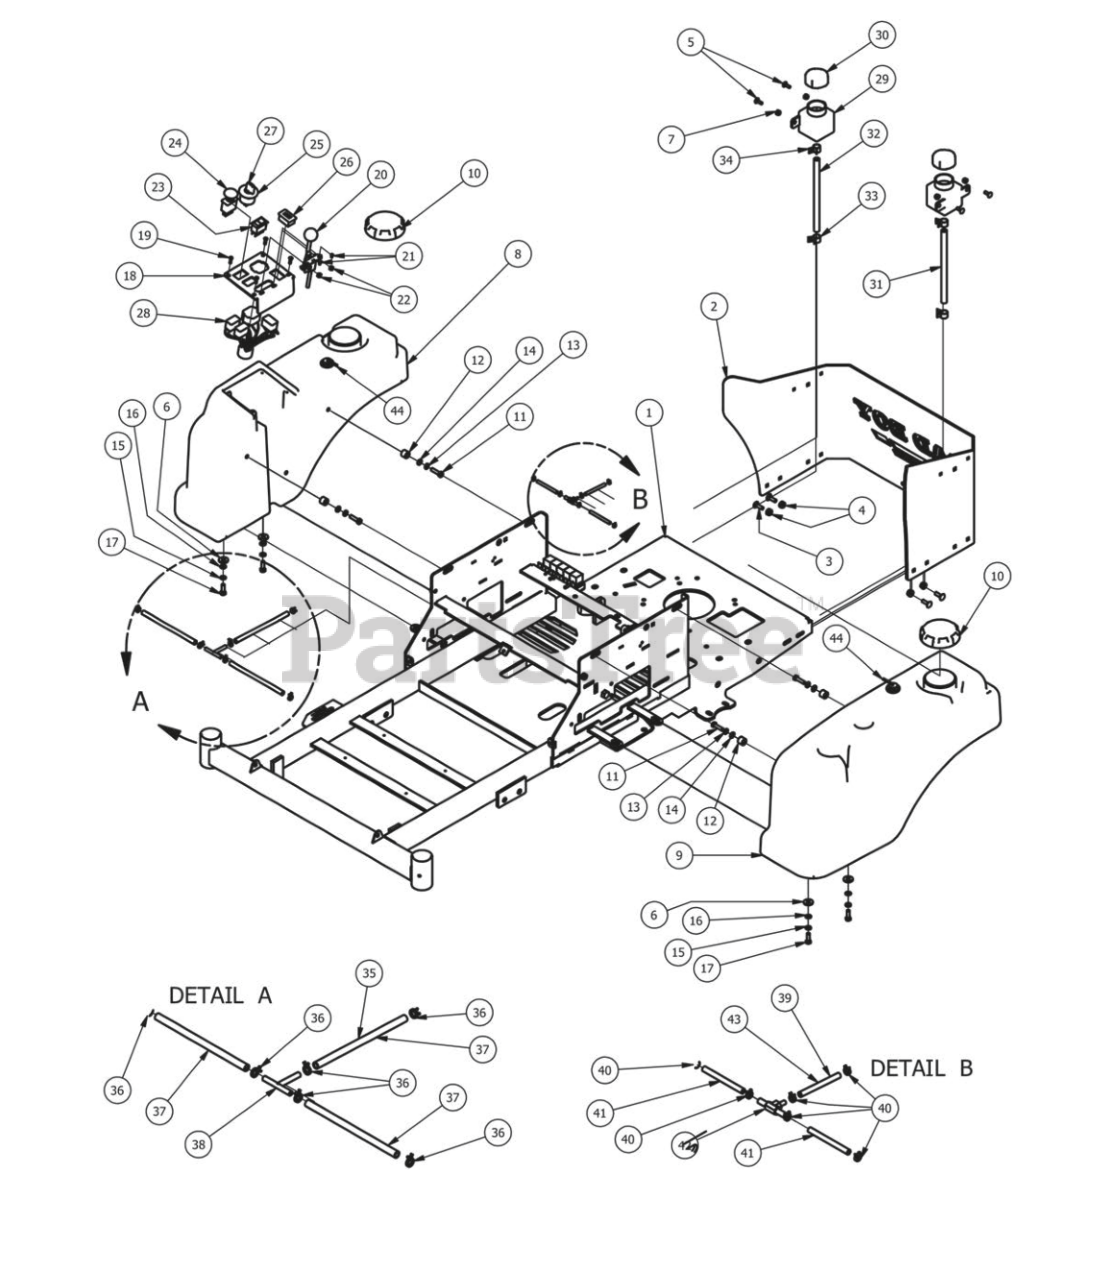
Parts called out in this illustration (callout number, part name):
1	ZT/CZT Frame 2013 Models
2	2013 ZT/CZT Rear Cover 27KO/26KA
3	5/16" x 1" Carriage Bolt
4	5/16-18 Nylon Flange Nut
5	1/4" x 3/4" Carriage Bolt
6	.360 ID Plastic Washer
7	1/4" Nylock Nut
8	Right Fuel Tank/Outlaw/2012/EPA
9	Left Fuel Tank/Outlaw/2012/EPA
11	5/16 x 1 1/4 Hex Bolt
12	.380x.735x.470 Nylon Spacer
13	5/16" Lock Washer
14	1/4" Flat Washer
15	5/16" Lock Washer
16	1/4" Flat Washer
17	5/16" x 1" Bolt
18	2013 ZT/CZT Control Panel
19	10-32 x 3/8" Button Socket Head Bolt
20	Throttle Lever Assembly
21	10-24 X 5/8 BS C/S 18-8 SS
22	10-24 Nylon Insert Locknut
23	Rocker Deck Lift Switch 2011
24	PTO Engager
25	Ignition Switch
26	Tachometer
27	Ignition Key
28	Harness-ZT Only-2008 and up
29	350ml Expansion Tank-CZT
30	Hydraulic Tank Cap
31	2013 ZT Hydraulic Hose Assembly
32	3/8 clear hose price per foot
33	1/2 Hose Clamp
34	3/8 hose clamp
35	2013 ZT Fuel Line Assembly
36	1/4 fuel clamp
37	1/4" fuel line hose
38	fuel line T
39	2013 ZT Air Hose Assembly
40	3/16 vinyl clamp
41	3/16 vinyl tubing
42	Brass fuel line T
43	3/16 vinyl tubing
44	Rollover Valve-White
